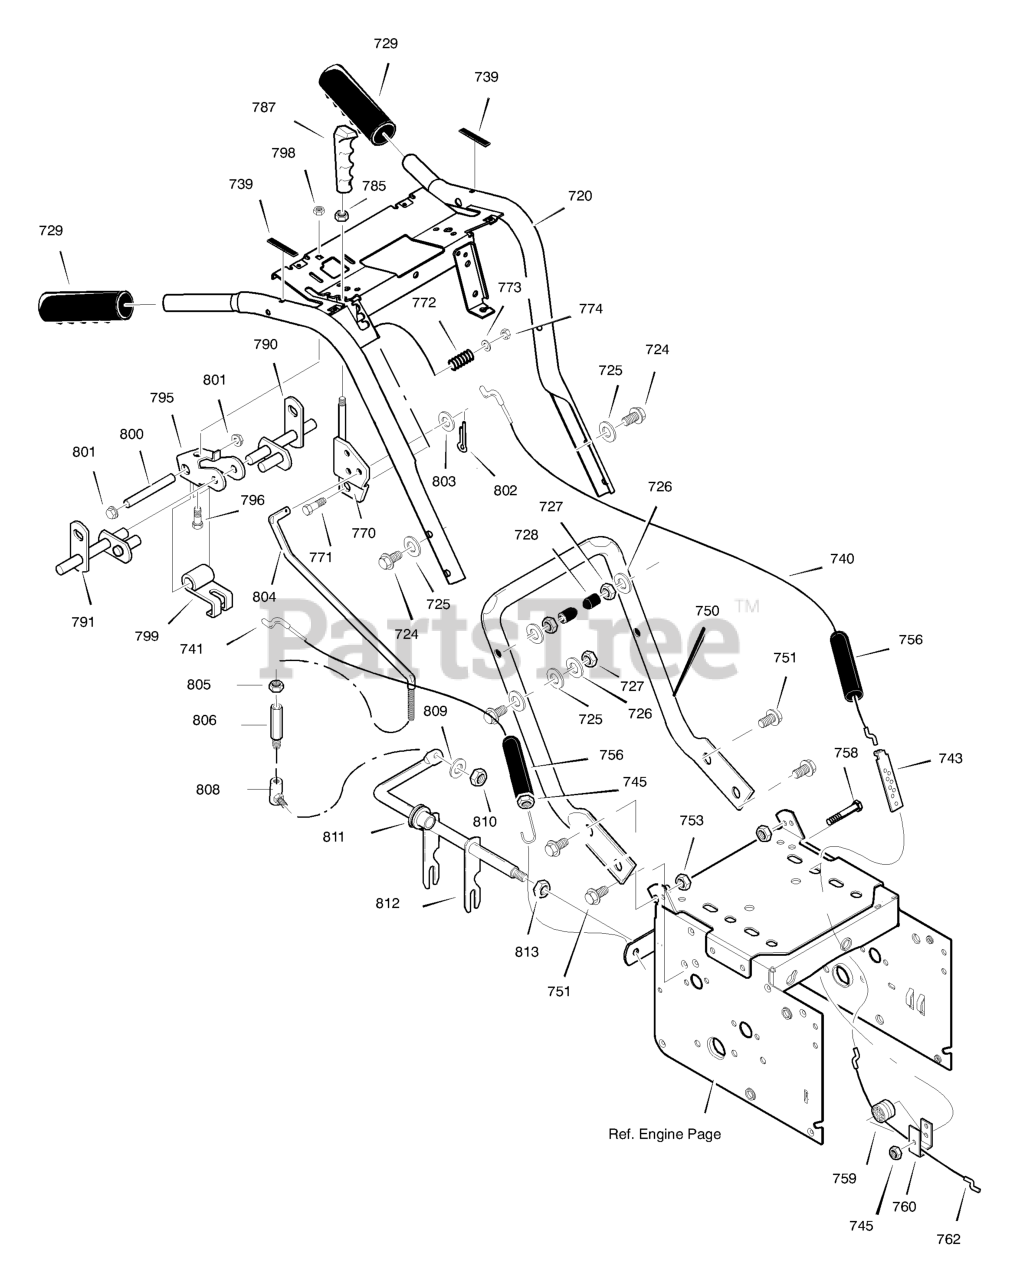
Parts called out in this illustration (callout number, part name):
720	ASSY, HANDLE
724	SCREW
725	WASHER, FLAT
726	WASHER
728	STOP, PLASTIC
729	GRIP, HANDLE
739	BUMPER
740	CABLE, CLUTCH AUGER DR
741	CABLE, AUGER CLUTCH
743	BRKT, CABLE ADJ
744	SPRING, CLUTCH
745	NUT, HEX
750	HANDLE, LOWER
751	SCREW
758	BOLT, HEX
759	SPOOL, CABLE
760	BRKT, SPOOL
762	CABLE, DRIVE
764	NUT, 5/16-18
765	BOOT, CABLE
770	BRACKET, SHIFT
771	SCREW, 3/8-16 x 3.00
773	WASHER, FLAT
774	NUT, HEX
785	NUT, HEX
787	KNOB, SHIFT
790	ROD, ASSY LH
791	ROD, ASSY RH
795	BRACKET, CAM
796	SCREW
798	NUT, NYLOCK
799	CAM LOCK
800	PIN, SPRING PIVOT
801	NUT, PUSH ON
802	PIN, COTTER
803	FLATWASHER
804	ROD, SPEED CTRL
805	NUT, 5/16-18
806	ADAPTER, ROD
808	BALLJOINT, STEEL
809	WASHER
810	NUT, 5/16-18
811	BEARING, FL
812	ROD, YOKE
813	RETAINER, RING
